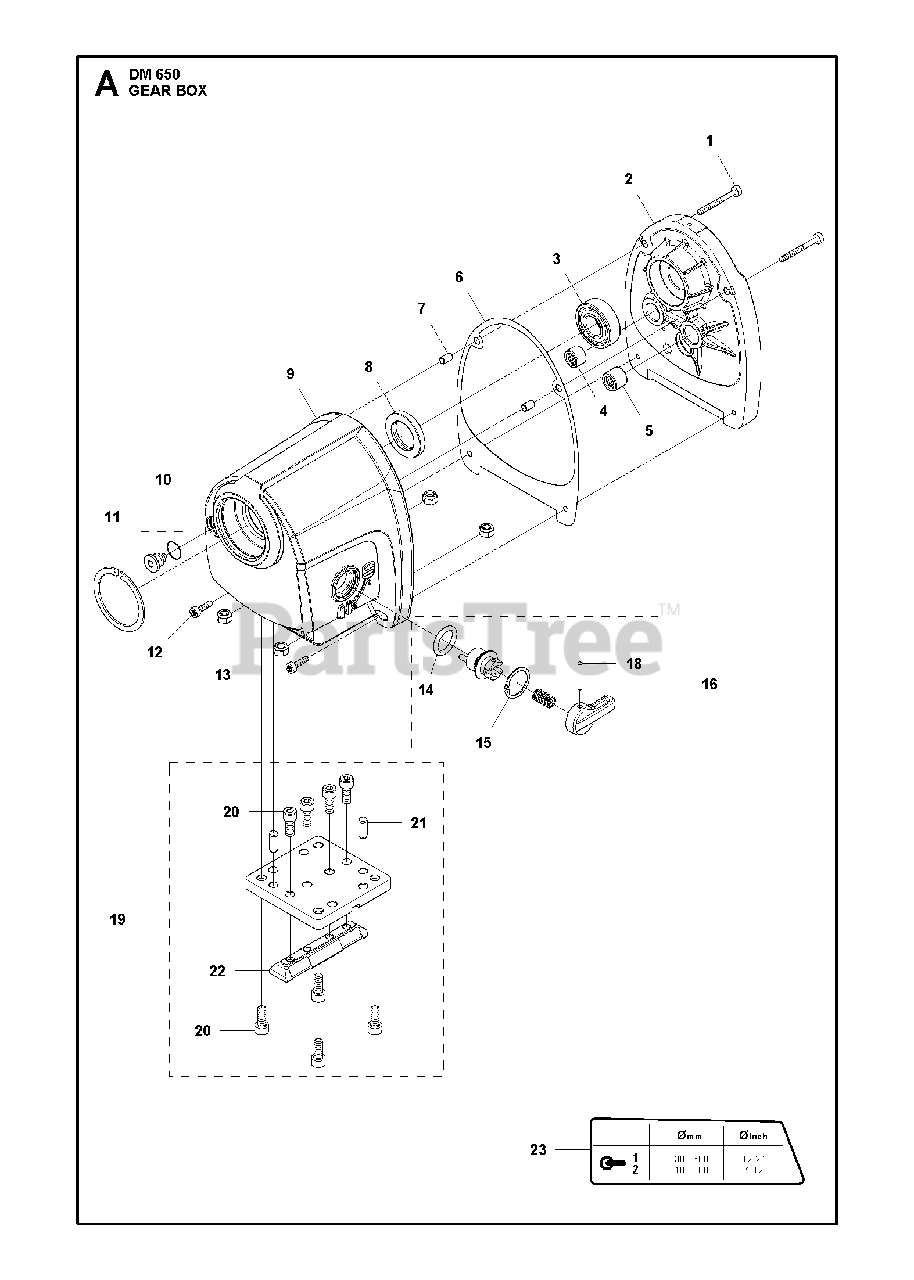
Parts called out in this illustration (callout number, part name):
3	BALL BEARING
4	NEEDLE BEARING
13	HEXAGON LOCKING NUT
18	PARALLEL PIN
21	PARALLEL PIN
